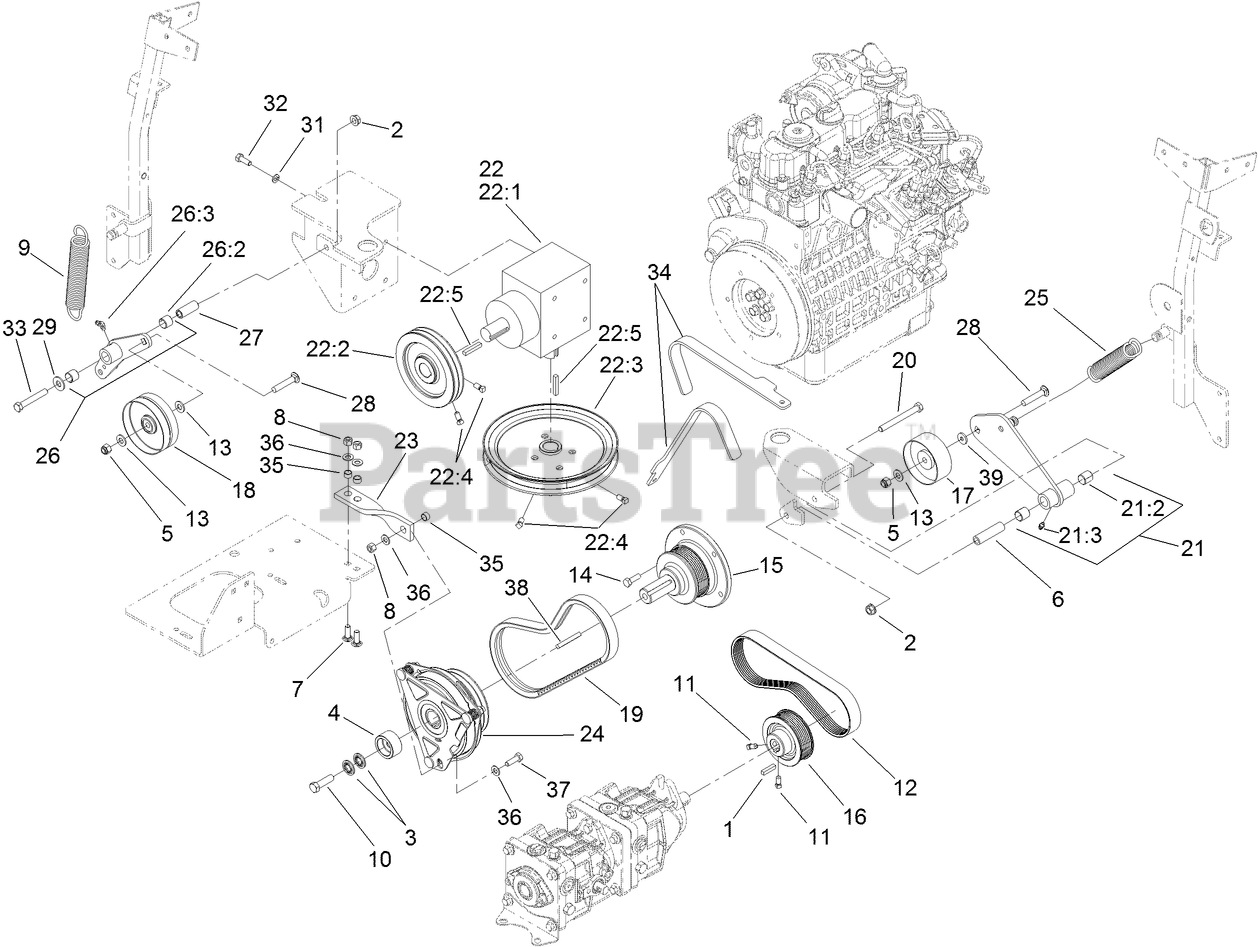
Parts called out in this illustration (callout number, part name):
2	NUT-HHF, WHIZ
3	WASHER-SPRING
4	RETAINER-CLUTCH
5	NUT-LOCK, NI
6	BUSHING-PIVOT, IDLER
7	SCREW-CARR
8	NUT-LOCK, NI
9	SPRING-EXTENSION
11	SCREW-SET
12	BELT-V
13	WASHER-FLAT
14	SCREW-HH
15	SHAFT-STUB
16	PULLEY
17	PULLEY-FLAT
18	PULLEY-FLAT
19	BELT-V
20	SCREW-HH
21	PUMP IDLER ARM ASM
21:2	SLEEVE-BEARING
21:3	FITTING-GREASE
22	GEARBOX ASM
22:1	GEARBOX-90 DEG
22:2	PULLEY
22:3	PULLEY
22:4	SCREW-SET
22:5	KEY-SQUARE
23	STRAP-STOP, CLUTCH
24	CLUTCH-MAGNETIC
25	SPRING-EXTENSION
26	GEARBOX IDLER ASM (W/BEARINGS)
26:2	SLEEVE-BEARING
26:3	FITTING-GREASE
27	BUSHING
28	SCREW-HH
29	WASHER-FLAT
31	SCREW-HH
32	SCREW-HH
33	SCREW-HH
34	TOOL-ALIGNMENT, PULLEY
35	SPACER
36	WASHER-PLAIN
37	SCREW-HH
38	KEY-SQUARE
39	WASHER
